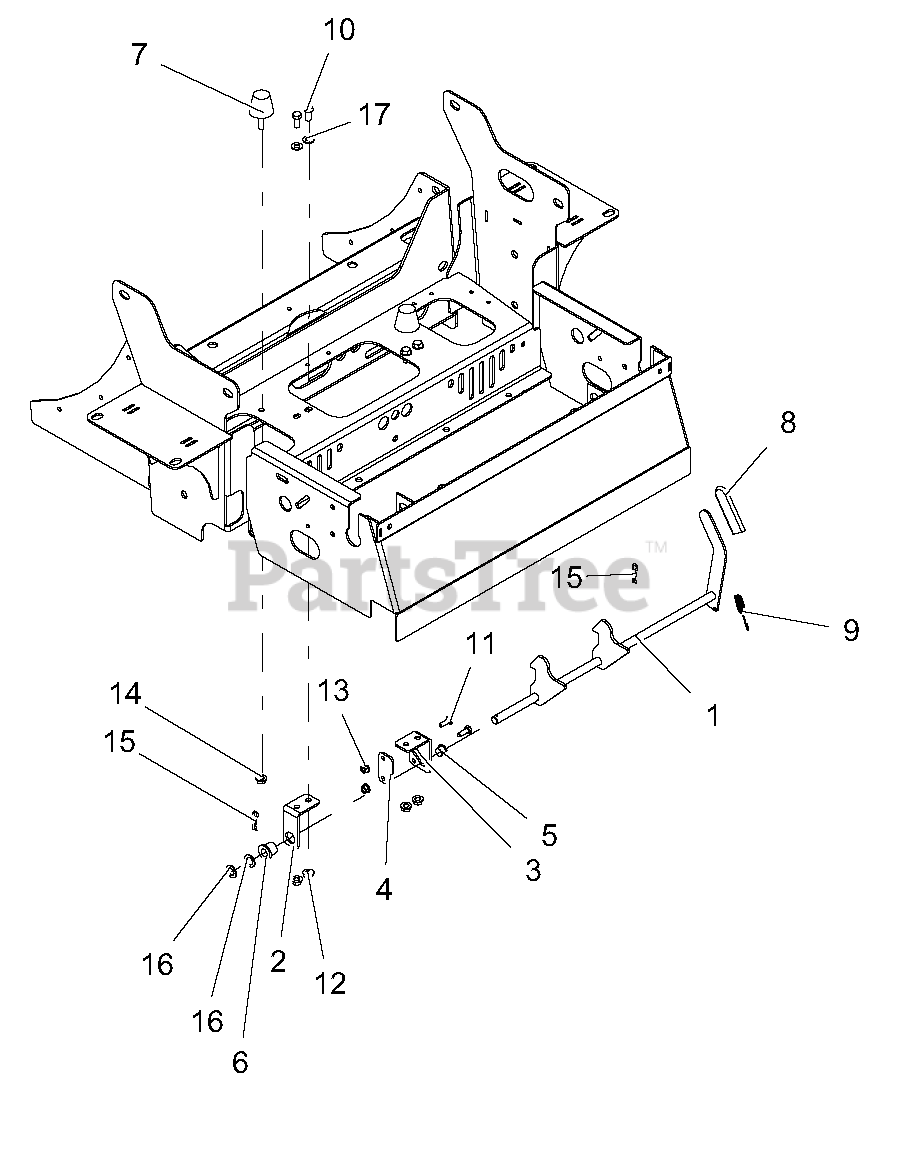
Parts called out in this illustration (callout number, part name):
1	WMT, SEAT LATCH
2	MOUNT, SEAT LATCH - RH
3	MOUNT, SEAT LATCH - LH
4	RETAINER-SEAT LATCH
5	BSHG, SPLIT NYLON
6	BSHG, FLANGE .515 X .750 X .745 X 1.00 NYLON
7	BUMPER, STUD MOUNTED CONE SHAPED
8	GRIP-VINYL-YELLOW .125 x 1.0 x 3.0
9	SPRG, EXTENSION
10	BLT-HEX .31-18X.75 GR5 YWZC
11	BLT-HEX .25-20X.75 GR5 YWZC
12	@NUT, LK-TOP-FLG .312-18 YWZC
13	@NUT, LK-TOP-FLG .25-20 YWZC
14	@NUT-SPNLK-FLG .312-18 YWZC
15	PIN-HAIR INT .08X.38X1.42 YWZC
16	WSHR-FL-STL .520X.827X.062 YWZC
17	@WSHR-FL-STL.344X.688X.065YWZC
